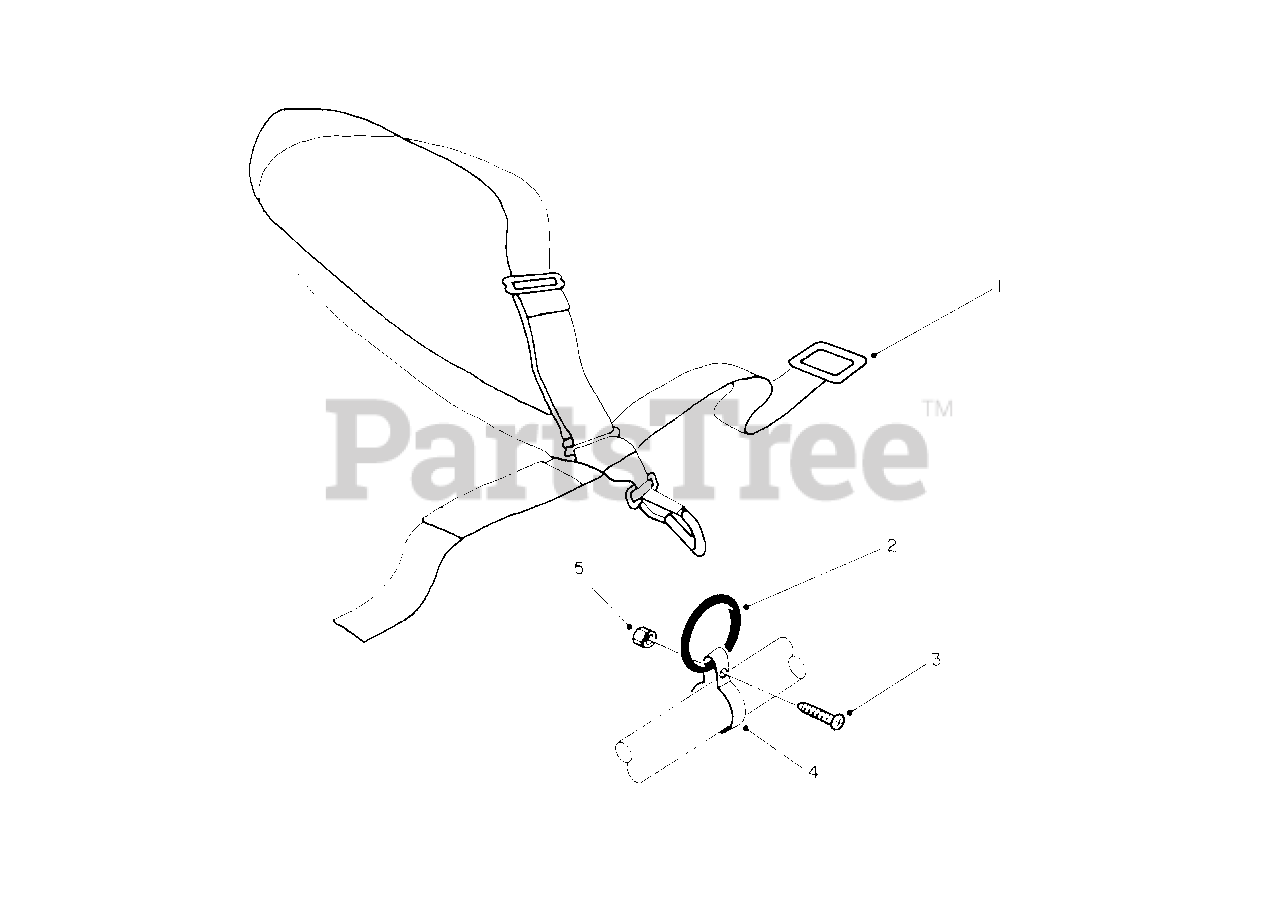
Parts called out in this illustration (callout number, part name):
1	Deluxe Harness
2	Ring
3	Screw
4	Clamp
5	Nut
